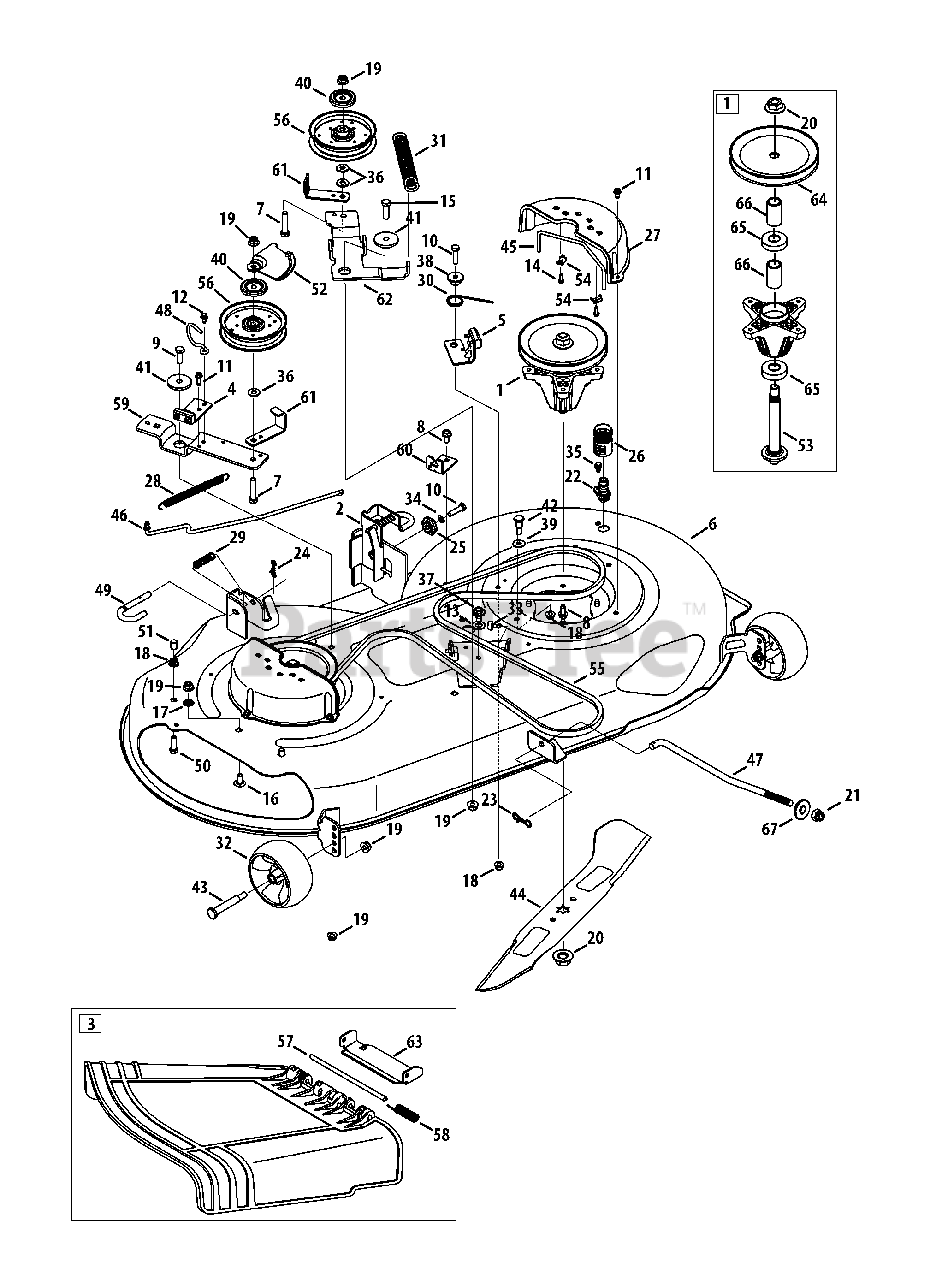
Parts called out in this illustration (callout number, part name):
1	Spindle Assembly, Pul 6.93 Dia
2	Bracket Assembly, Deck Hanger, LH
3	Chute Deflector Assembly
4	Brake Assembly, Deck, 42/46
5	Brake Assembly, Deck, 46"
6	Deck Assembly, 46t, 2w
7	Hex Screw, 3/8-16 x 2.00
8	Screw, Self-tapping, 5/16-18, .750
9	Hex Screw, 3/8-16, 1.00, Gr5, Std
10	Hex Screw, 5/16-18, 1.25, Gr5, Std
11	Screw, Self-tapping, 1/4-20, 0.500
12	Screw, Self-tapping, 1/4-20, .750
13	Washer, Flat, .474 x .879 x .064
14	Screw, B, #10-16, 0.625
15	Hex Screw, 3/8-16 x 1.25
16	Bolt, Carriage, 3/8-16, 0.75, Gr1
17	Nut, Push, 3/8
18	Nut, Flange Lock, 5/16-18, Nylon
19	Nut, Flange Lock, 3/8-16, Nylon
20	Nut, Flange, 5/8-18
21	Nut, Lock, 1/2-13
22	Deck Wash Nozzle
23	Bow-Tie Cotter Pin
24	Bow-Tie Cotter Pin, 72
25	Gear, Deck Adjustment
26	Water Nozzle Adapter
27	Belt Cover, Universal
28	Spring, Extension, .62 x 6.12
29	Spring, Compression, .535 x 1.751
30	Spring, Torsion, .992 I.D X 1.17 O.D
31	Spring, Extension, 1.05 X 6.346
32	Wheel, Deck, 5.0 Dia Ball
33	Bumper, .62 Dia X .3
34	Washer, Lock, 5/16, Regular Duty
35	Shoulder Screw, 1/4-20 x 0.50
36	Washer, Flat, .385 x .870 x .092
37	Shoulder Spacer, .43 x .29, 5/16-18
38	Shoulder Spacer, .50 x .145
39	Washer, Flat, .343 X .880 X .062
40	Pulley Cap
41	Shoulder Spacer, .8840 X .190
42	Shoulder Screw, .437 Dia. X .54
43	Bolt, Shoulder, .496 x 2.50, 3/8-16
44	Blade, Cut, 23.25" 2-In-1, Econ
45	Rod, Keeper, Belt
46	Rod, Control, Brake 46"
47	Rod, Lift, Deck, Medium
48	Rod, Keeper, Belt, 42s 46t
49	Rod, Deck Release
50	Hex Cap Screw, 5/16-18 x 1.00
51	Cap, .290 x .500
53	Spindle Shaft, 6.05 LG.
54	Clamp, Casing
55	Belt, V-Typ, A Sec
56	Pulley, Idler, 4.25"Dia
58	Torsion Spring
59	Bracket, Idler, Pivot, 46
60	Bracket, Cable, Deck Engagement
61	Bracket, Guard, Belt, 4.25 Pulley
62	Bracket, Idler, 46" Lh
63	Chute Bracket
64	Deck Pulley, 6.93 DIA
65	Ball Bearing, .787ID X 1.85 ODX.551
66	Spacer, .792 X 1.060 X 1.860 LG
67	Pivot Cup, Deck Lift
